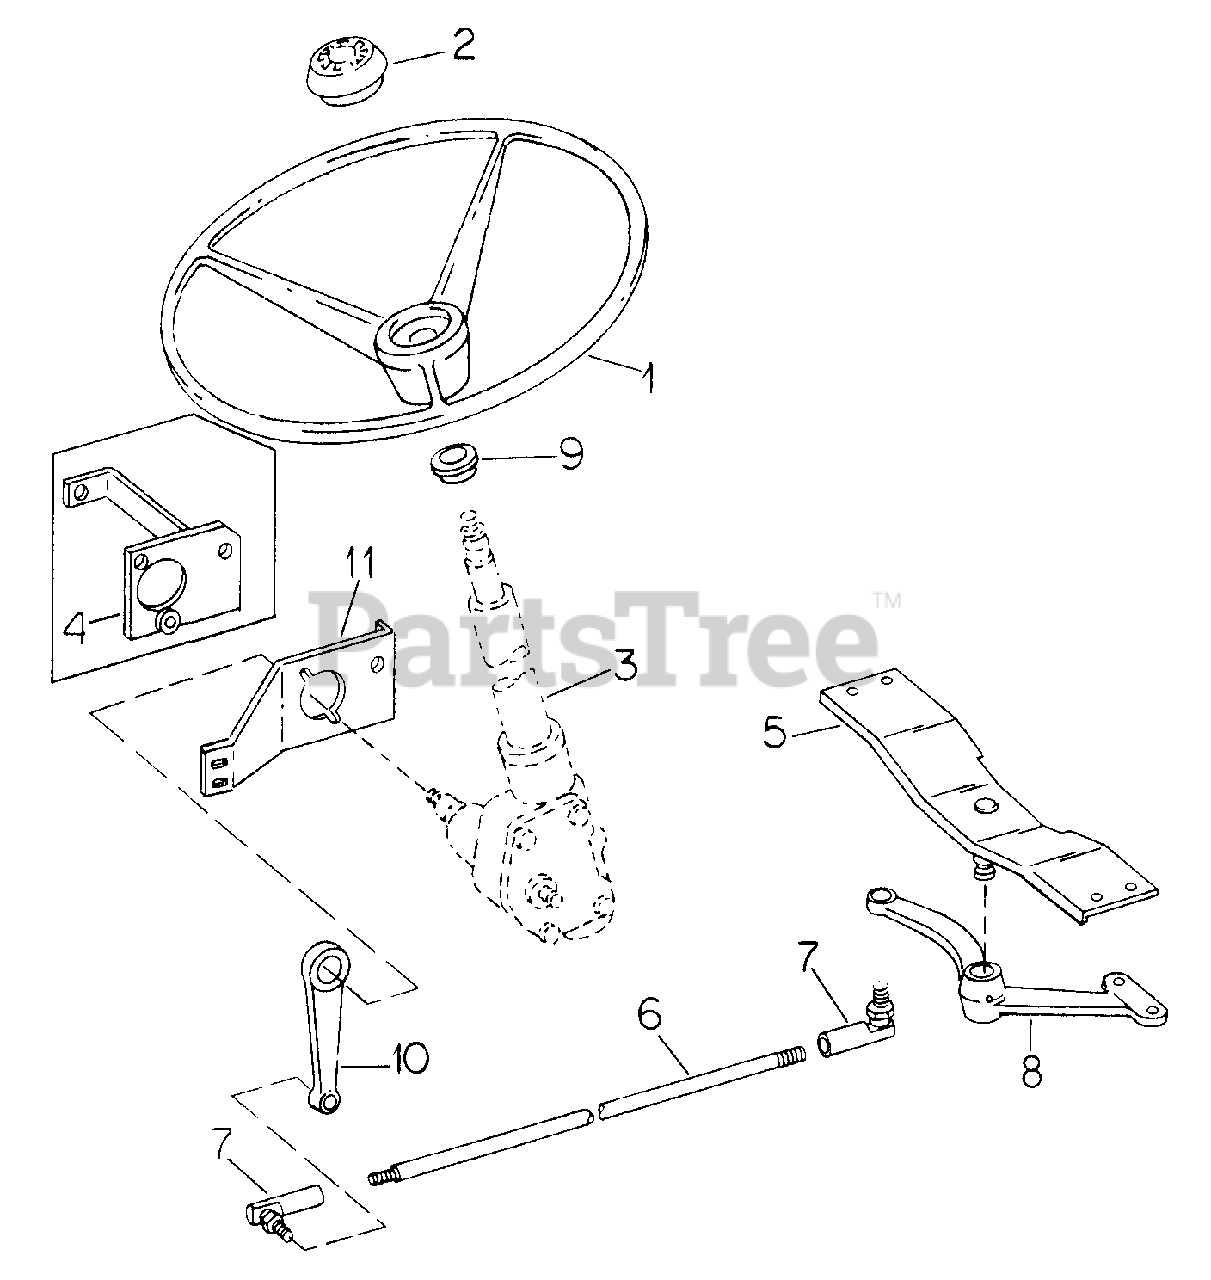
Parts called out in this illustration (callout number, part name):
1	WHEEL, STEERING
2	CAP, STEERING
3	GEAR ASSY STEERING
4	PLATE ASSY, STEERING SUPPORT
5	SUPPORT ASSY, STEERING LEVER
6	ROD, DRAG LINK
7	JOINT, DRAG LINK BALL
8	LEVER, STEERING
9	BEARING, COLUMN UPPER
10	ARM, STEERING
11	SUPPORT, STEERING GEAR
